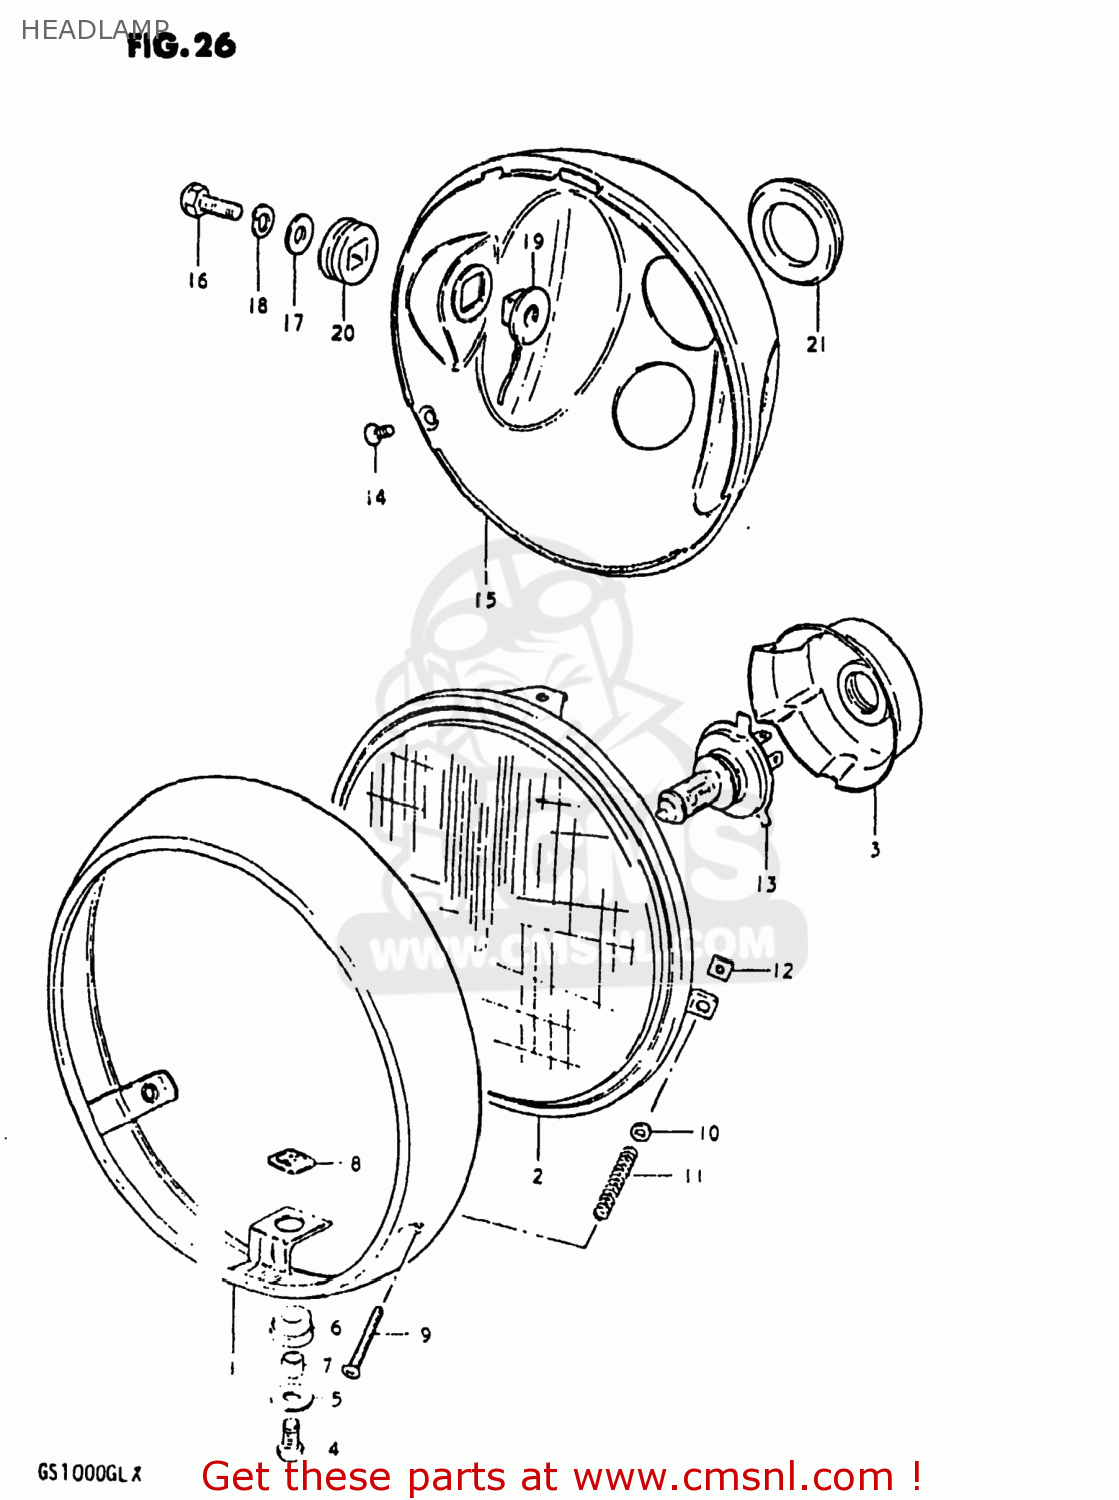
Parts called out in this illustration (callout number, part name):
1	RIM
2	LAMP UNIT
3	COVER,SOCKET
4	SCREW
5	WASHER
6	CUSHION
7	SPACER
8	NUT
9	SCREW
10	WASHER
11	SPRING,HEADLAMP ADJUST
12	NUT,HEADLAMP ADJUSTER
13	BULB(12V60/55W,H4)
14	SCREW
